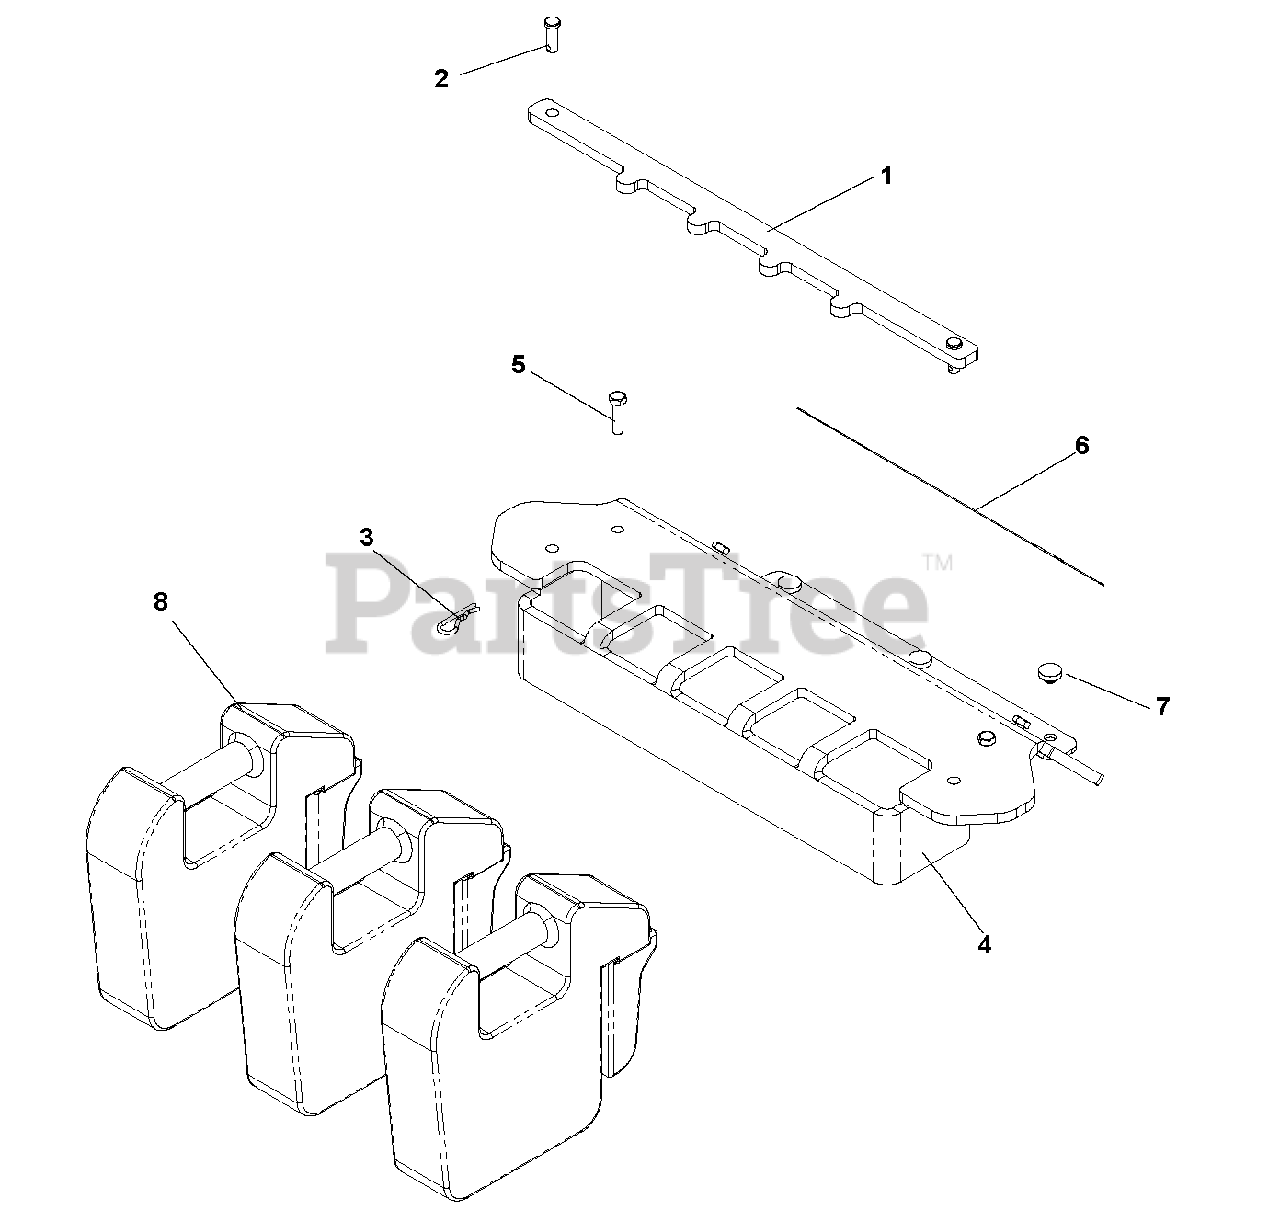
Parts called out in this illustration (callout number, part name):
1	HOLD DOWN, WEIGHT BAR
2	CLEVIS PIN
3	RETAINER SPRING
4	WEIGHT BAR
5	HCS 5/16C X 1 1/4
6	ANTI-SKID PAD
7	GROMMET, BUMPER
8	FRT WEIGHT CAST PZ DFS
